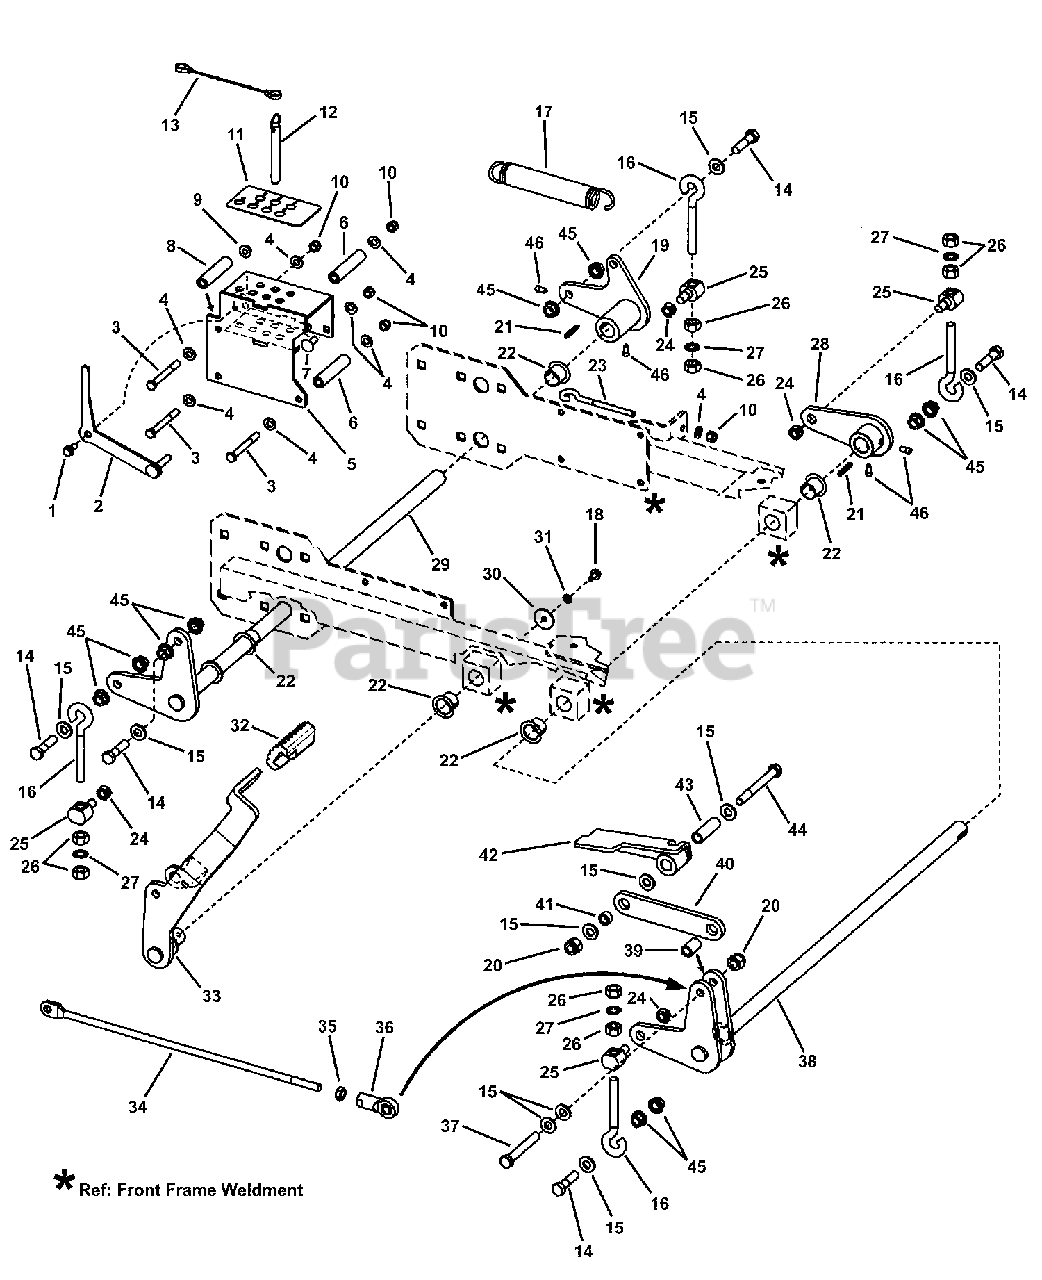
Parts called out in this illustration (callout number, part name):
1	SHOULDER BOLT, 5/16-18
2	WELDMENT, Transport Lever
3	SCREW, 3/8-16 x 4-1/2 Hex Head Cap, GR 5
4	WASHER, 3/8" Flat SAE
5	WELDMENT, Detent
6	SPACER LIFT
7	BOLT, 3/8-16 x 1" Square Neck Carriage, GR 5
8	DETENT SPACER, Upper
9	NUT, 5/16-18 Large Flange Hex Center Lock
10	NUT, 3/8-16 HEX NYLON LOCK
11	DECAL, Detent Channel
12	CLIP, Roll Pin, 1/2"
13	STRAP, Tether
14	SCREW, 1/2-13 x 2" Hex Head Cap, GR 5
15	WASHER, .531 I.D. Flat
16	EYEBOLT, 1/2-13 Open
17	SPRING, Extension, Lift Assist
18	SCREW, 5/16-18 x 5/8" Hex Washer Self-Tap
19	WELDMENT, Bell Crank
20	NUT, 1/2-13 Hex Nyloc
21	KEY, 3/16" Square x 1-1/2"
22	BUSHING, Teflon
23	EYEBOLT, 3/8-16 x 3"
24	NUT, 1/2-13 HEX SIDE LOCK
25	SWIVEL, Rear Lift (1/2-13 thread)
26	NUT, 1/2-13 HEX
27	WASHER, 3/8" Internal Tooth Lock
28	WELDMENT, Front Lift LH
29	WELDMENT, Rear Lift
30	WASHER, 5/16" Belleville
31	WASHER, 5/16" Split Lock
32	PEDAL, Rubber
33	WELDMENT, Foot Assist
34	ROD, Transfer (1/2-20 thread)
35	NUT, 1/2-20 Hex Jam, GR 5 or B
36	ROD END, 1/2-20 Female
37	BOLT, 1/2-13 x 3-3/4" Hex Head Cap
38	WELDMENT, Front Deck Lift
39	SPACER
40	LINK PLATE
41	SPACER, Bearing
42	WELDMENT, Height Adjuster
43	SPACER, Bearing
44	BOLT, 1/2-13 x 4-1/2" Hex Head, GR 5
45	NUT, 1/2-13 Hex Flange Lock GR 5
46	SET SCREW, 5/16-18 x 1/2" Square Head Cup Point
